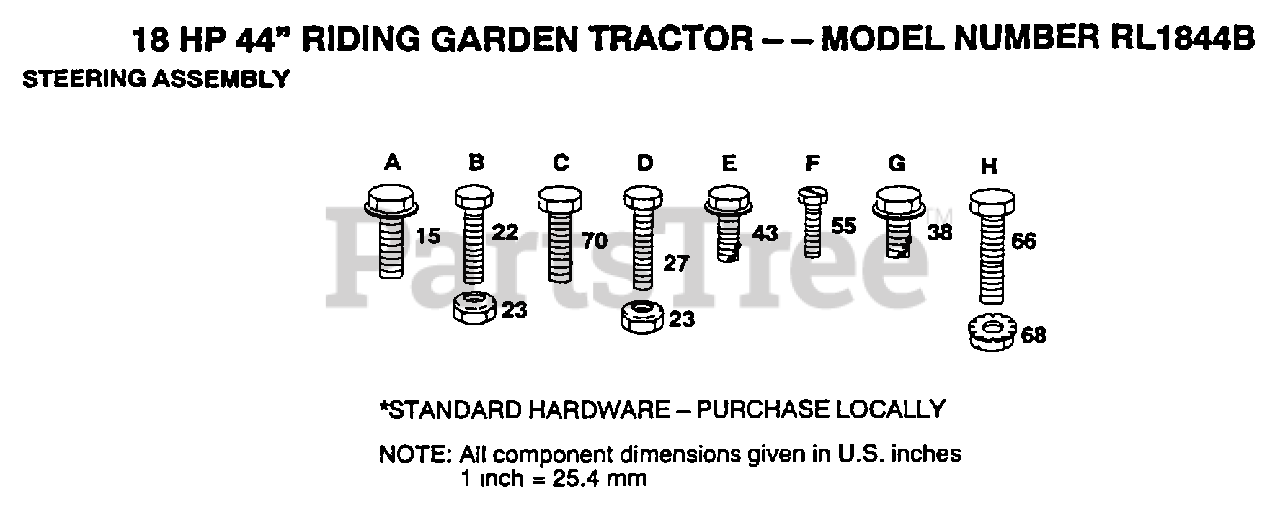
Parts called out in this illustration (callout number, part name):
15	SCREW SPECIAL
22	SCREW
27	BOLT
38	SCREW LT
43	SCREW LT
66	BOLT
68	NUT
70	SCREW
